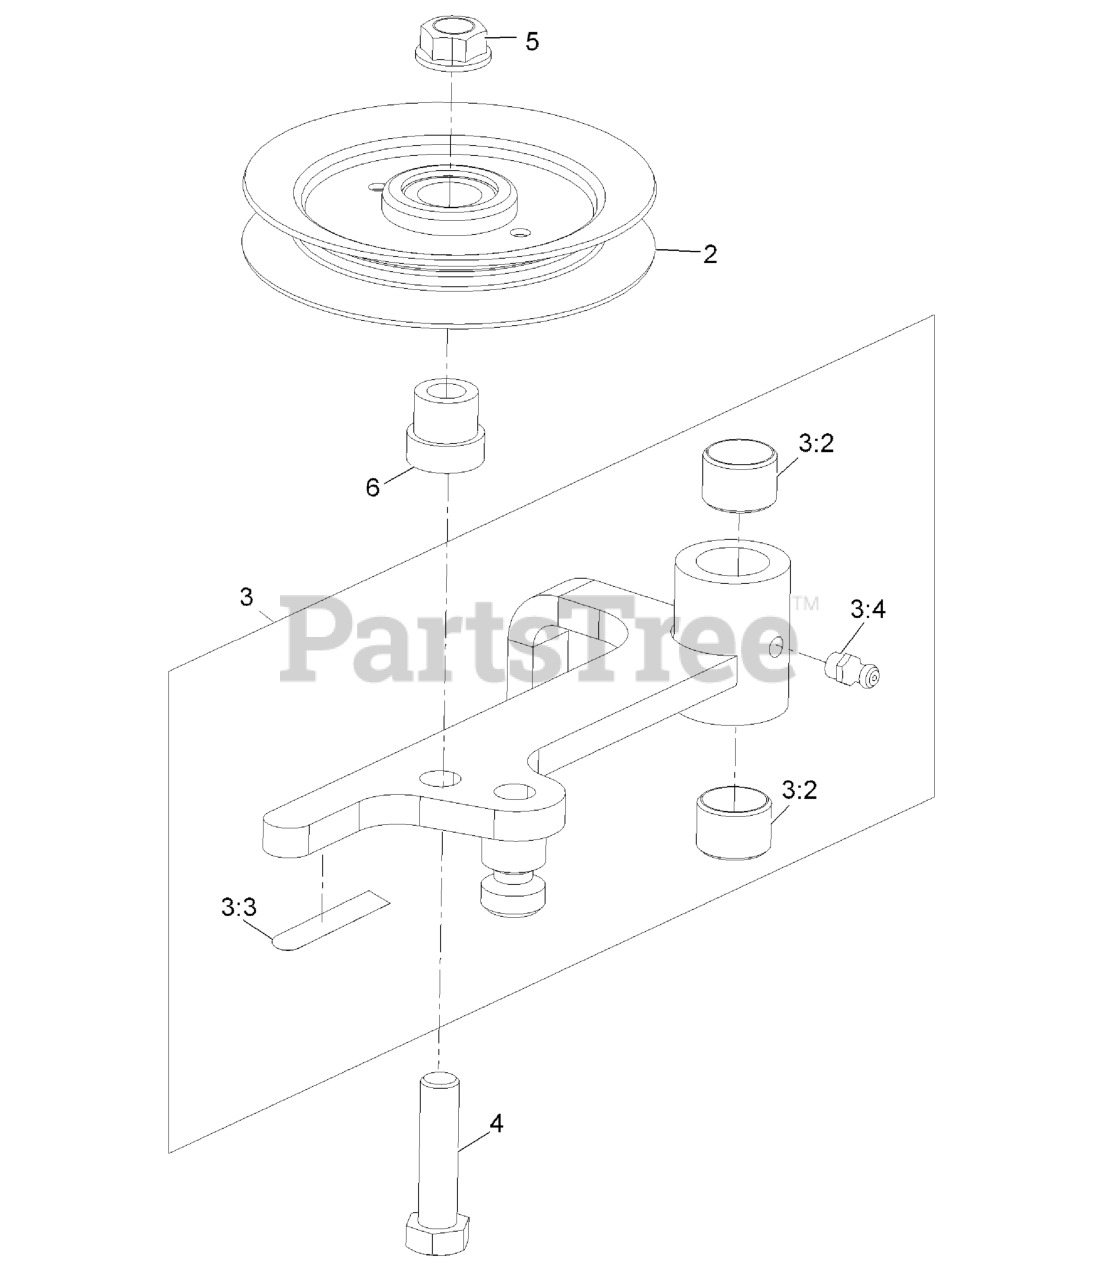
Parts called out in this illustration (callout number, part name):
3	ASM, IDLER ARM - SERVICE ONLY
3:2	BUSHING
3:3	DECAL-WARNING
3:4	FITTING-GREASE
4	SCREW-HH
5	NUT-HHF, WHIZ
6	HUB,SPACER
